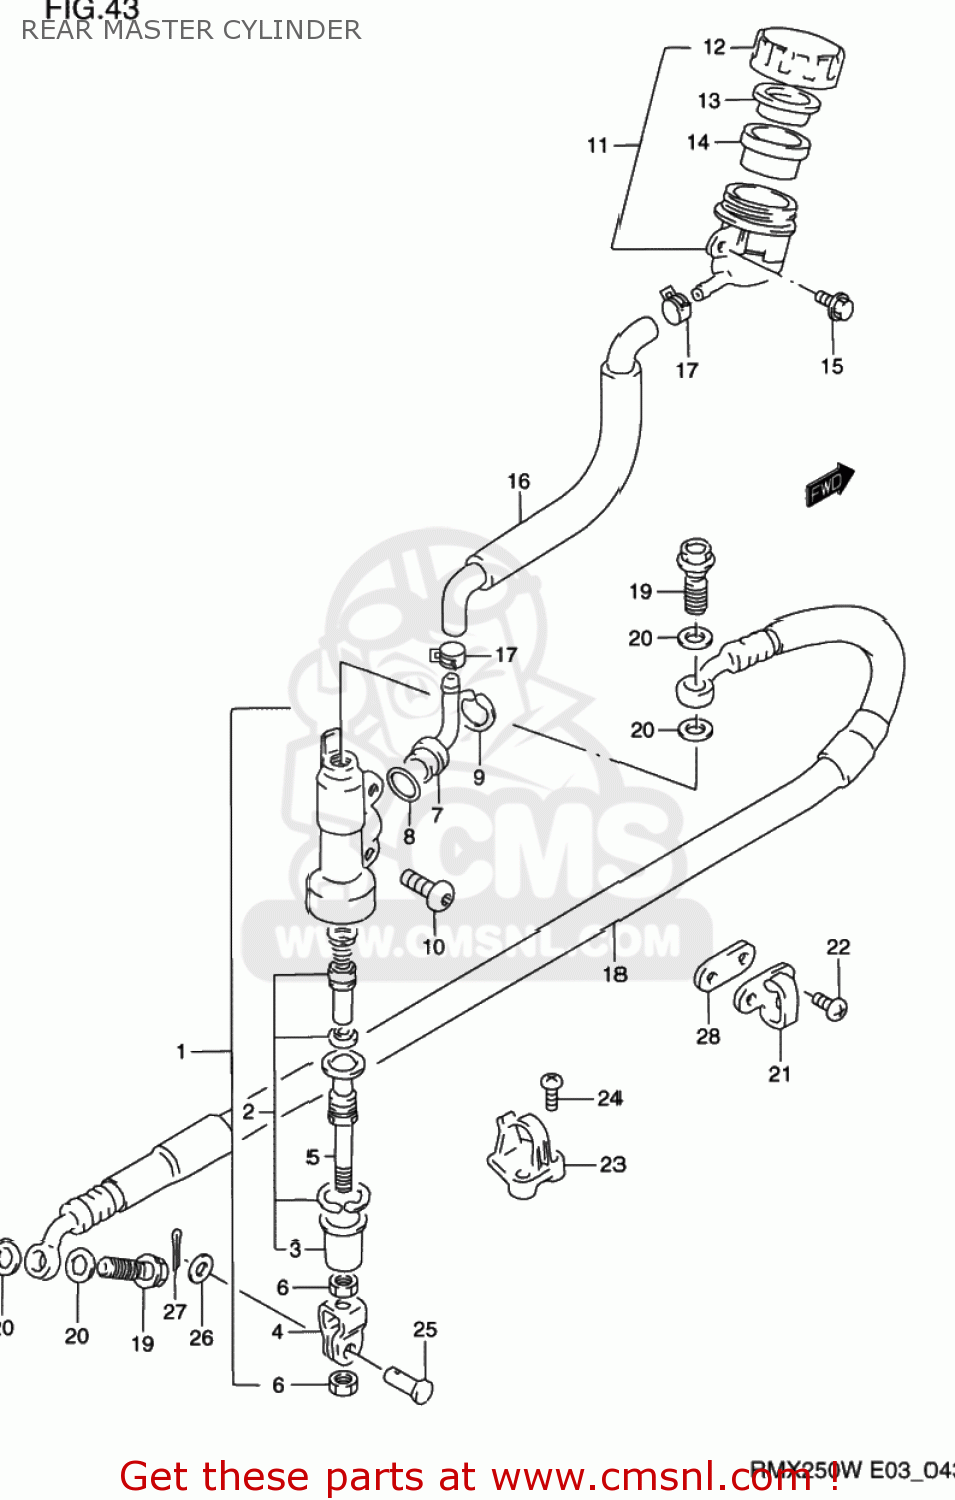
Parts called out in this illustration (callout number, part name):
1	CYLINDER ASSY,RR MASTER
2	PISTON/CUP SET
3	BOOT
4	YOKE
5	ROD,PUSH
6	NUT
7	CONNECTOR
8	O RING
9	CIRCLIP
10	SCREW(6X16)
11	TANK ASSY,RR BRAKE RESERVOIR
12	CAP
13	PLATE
14	DIAPHRAGM
15	BOLT
16	HOSE,TANK
17	CLAMP,RESERVOIR HOSE
18	HOSE,RR BRAKE
19	BOLT UNION
20	WASHER(10X15X1.5)
21	GUIDE,RR BRAKE HOSE
22	SCREW
23	GUIDE,RR BRAKE HOSE
24	SCREW
25	PIN(8X20)
26	WASHER(8.5X13X1.6)
27	PIN
28	SEAT,RR BRAKE HOSE GUIDE
